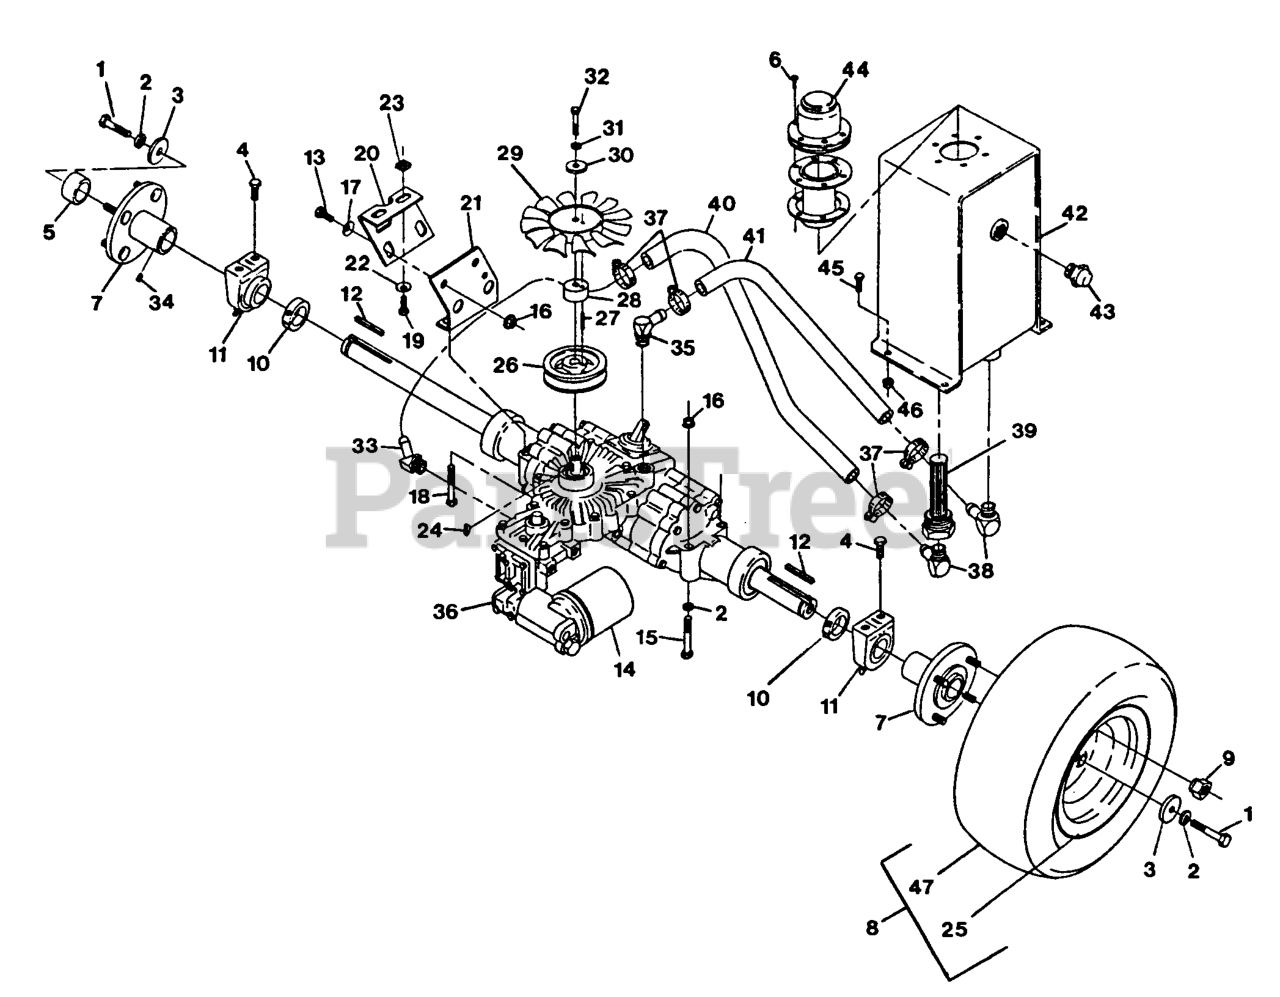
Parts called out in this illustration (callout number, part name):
8	WHEEL AND TIRE ASM
11	BEARING,PILLOW BLOCK
12	KEY,MACH HRD
28	SPACER,FAN
29	FAN,7"OD/10BLADE
30	WASHER-RETAINER, PULLEY
31	WASHER-LOCK
33	ELBOW-45DEGOR/HSEBRB
37	CLAMP-HOSE
39	STRAINER,SUCTION
40	HOSE,HYDRAULIC 16.5
41	HOSE,HYDRAULIC 8.0
43	OIL EYE,HYDRAULIC TANK
44	BREATHER,FILLR & CAP
